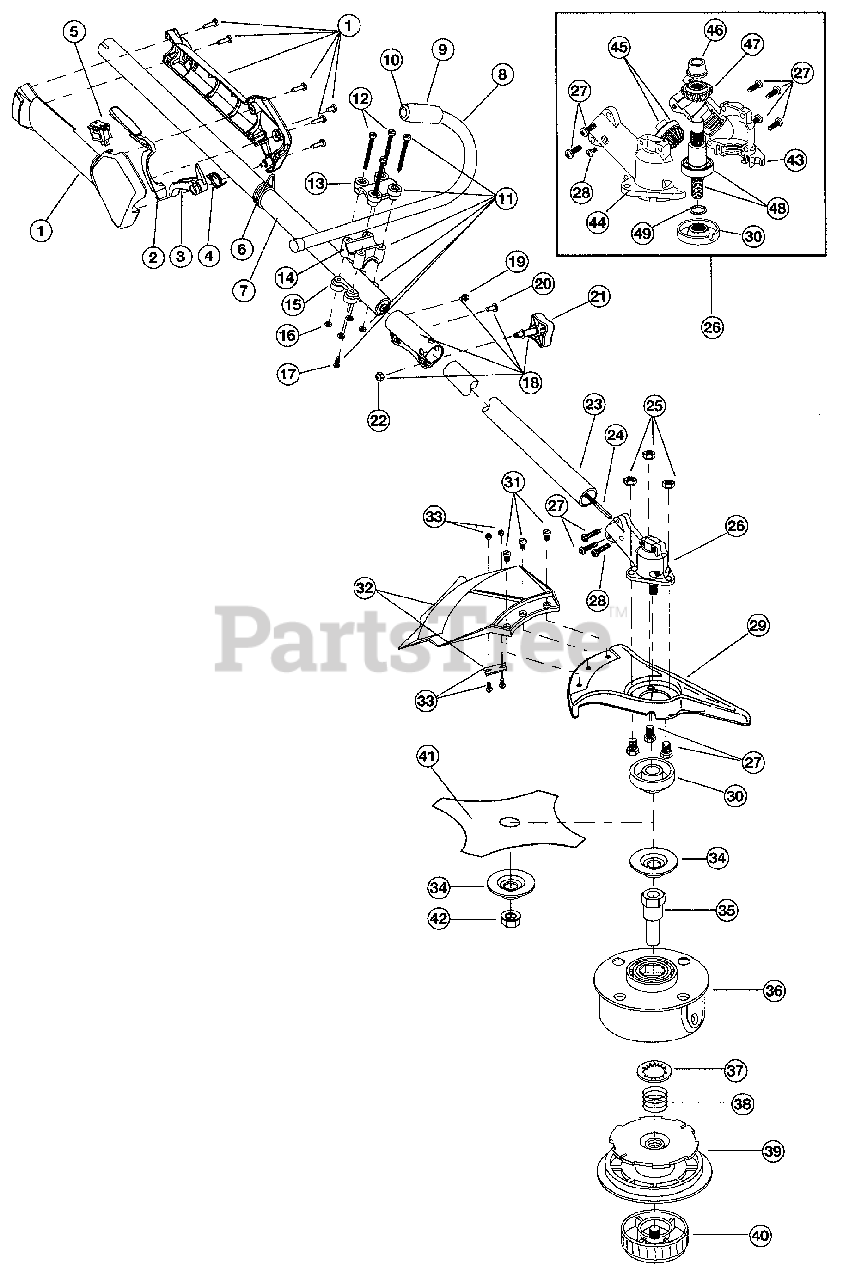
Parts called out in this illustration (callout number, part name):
1	Throttle Housing and Trigger Assembly
2	Throttle Trigger Lock-Out
3	Throttle Trigger
4	Throttle Trigger Spring
5	Switch Assembly
6	Harness Clip
7	Upper Drive Shaft Housing Assembly
8	J-Handle Assembly
10	Tube Closure
11	Handle Bracket Assembly
13	Upper Handle Clamp
14	Middle Handle Clamp
15	Lower Handle Clamp
17	Anti-Rotation Screw
18	Click-Link Coupler
21	Adjustment Knob
22	Knob Retaining Nut
23	Lower Drive Shaft Housing Assembly
24	Lower Flexible Drive Shaft
25	Shield Mount Screw Assembly
26	2 piece Gearbox Assembly
27	Gearbox Screw
28	Anti-Rotation Screw
29	Blade Shield/Shield Mount
30	Blade Driver
31	Shield Mounting Screw
32	Shield and Blade Assembly
33	Blade Assembly
34	Retaining Washer
35	Spool Shaft
36	Outer Spool and Eyelet Assembly
37	Retainer
40	Bump Head Knob Assembly
41	4-Tooth Blade
42	Nut
43	Left Housing
44	Right Housing
45	Pinion Gear Assembly
46	Output Shaft Bushing
47	Output Shaft Gear
48	Output Shaft Assembly
49	O-Ring
